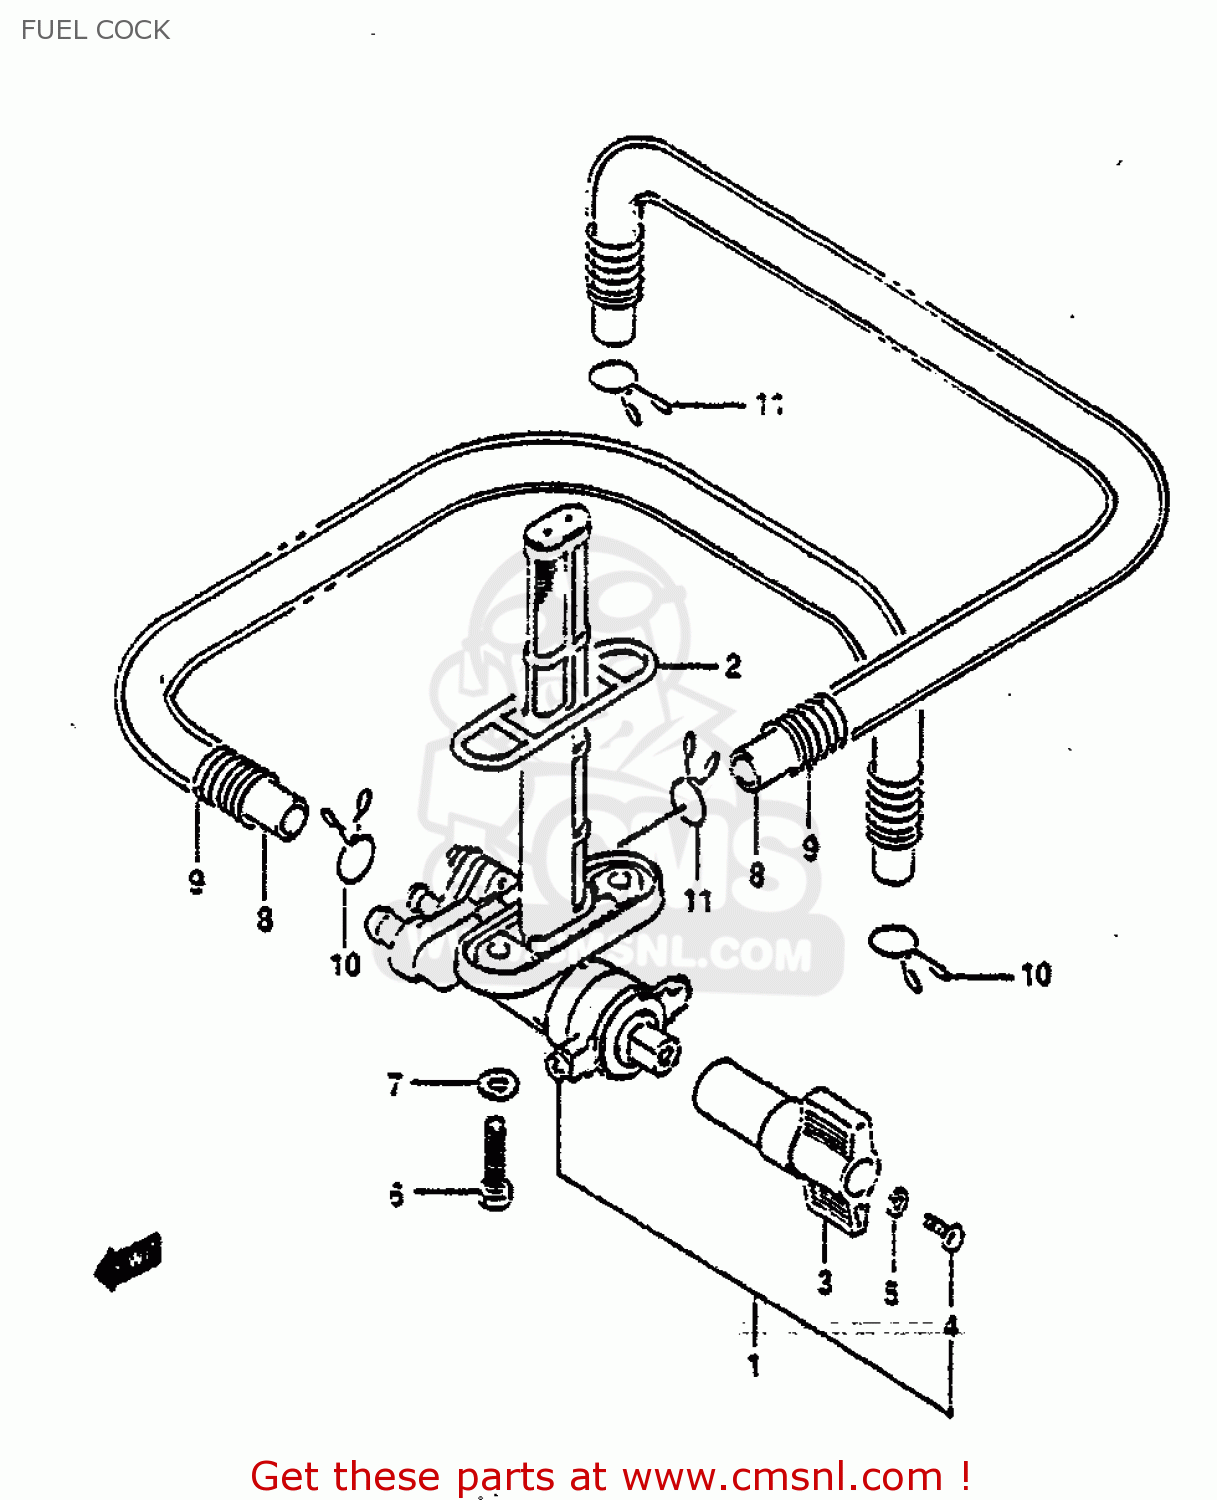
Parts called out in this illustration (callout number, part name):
1	COCK ASSEMBLY,FUEL
2	O RING,FUEL TANK JOINT
3	LEVER,FUEL COCK
4	SCREW
5	LOCK WASHER
6	BOLT(6X20)
7	GASKET(6.4X11.5X0.8) (NAS)
8	HOSE
9	SPRING
10	CLIP
11	CLIP
